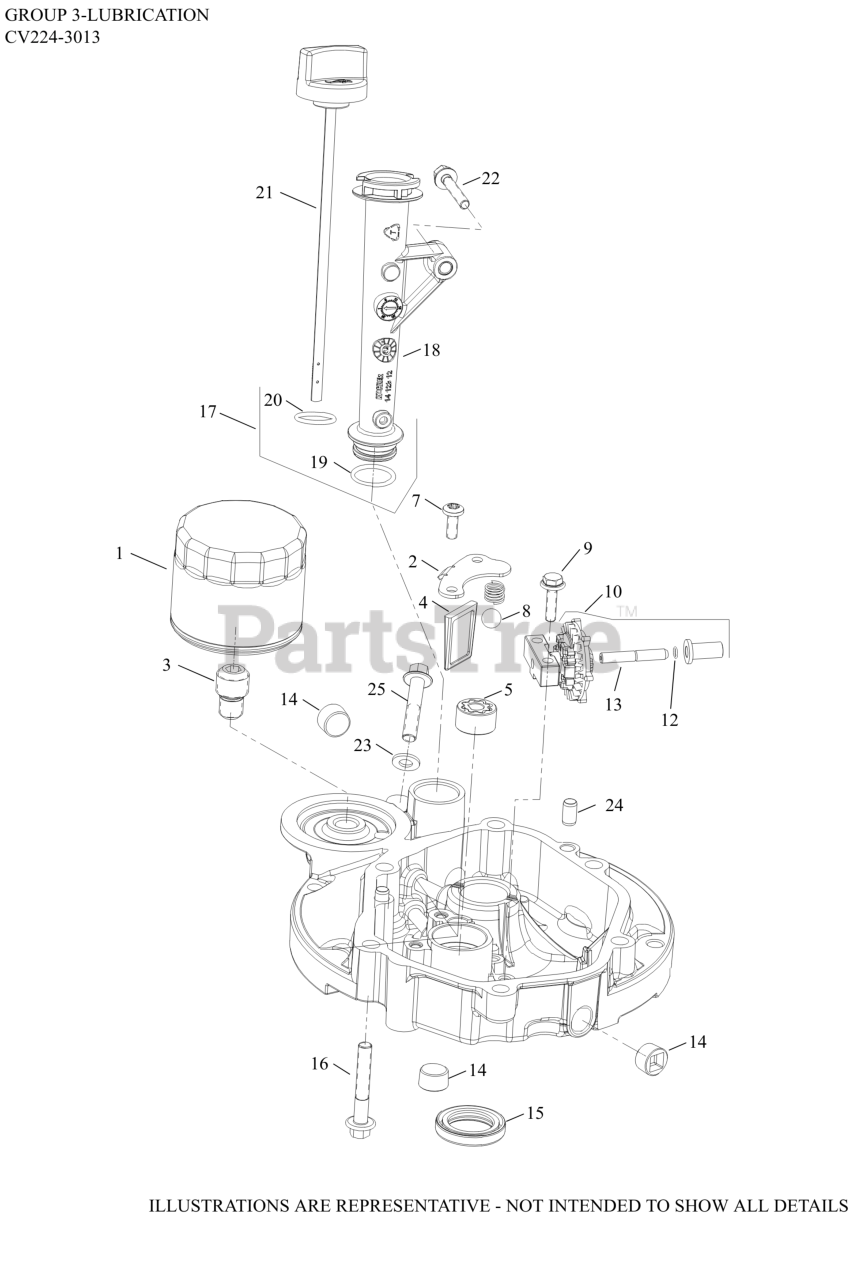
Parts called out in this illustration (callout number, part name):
1	FILTER, OIL
2	COVER, OIL PUMP SCREEN
3	NIPPLE, OIL FILTER
4	SCREEN, OIL
5	PUMP ASSEMBLY, OIL (GE-ROTOR)
7	SCREW, M6 X 16
8	BALL, STEEL COMPOSITE
9	SCREW, M6 X 22
10	GOVERNOR GEAR, ASSEMBLY
12	CLIP, GOVERNOR GEAR-DISCONTINUED
13	SHAFT, GOVERNOR GEAR-DISCONTINUED
14	PLUG, PIPE (W/SEALANT)
16	SCREW, HEX FLANGE (M8)-USE 25 086 456-S
17	KIT, DIPSTICK AND TUBE-(#1412320S)
18	TUBE ASSEMBLY, OIL FILL
19	O-RING, OIL FILL TUBE
20	O-RING (CAP)
21	CAP, DIPSTICK ASSEMBLY
22	SCREW, HEX FLANGE (M6)-(#25086435S)
23	WASHER, CLEAN OIL SCREW
24	PIN, DOWEL (8mm)
25	SCREW, CLOSURE PLATE
